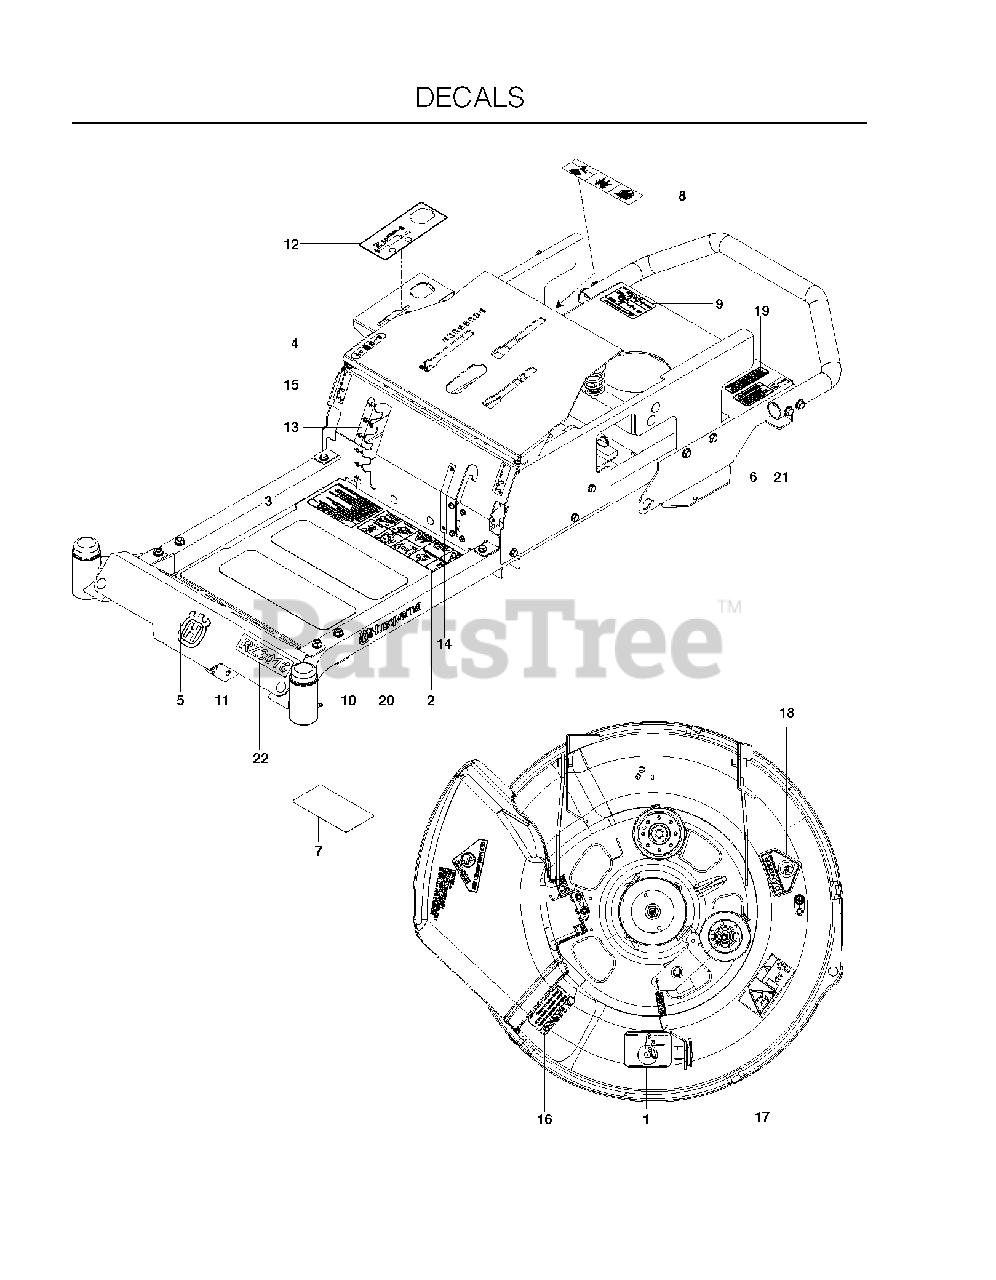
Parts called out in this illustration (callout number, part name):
1	DECAL, BELT ROUTING
2	DECAL, SAFETY WARNING
3	DECAL, WARNING
4	DECAL, PARK BRAKE
5	DECAL.AUGER.HUSQ.CROWN.SNOW
6	DECAL, PROP. 65
7	DECAL, SERVICE
8	EURO DECAL-BATTERY WARNIN6
9	DECAL, DO NOT TOW
10	ANTI-SKID PAD
12	DECAL, CONTROL PANEL HUS
13	DECAL, DECK HEIGHT
14	DECAL, BLADE ENGAGEMENT
15	DECAL, MOTION CONTROL
16	DECAL, CAUTION
17	DECAL, EURO SEVERING
18	DECAL, CPSC
19	DECAL, WARNING SPARK ARRESTOR
20	RP.DECAL.BADGE.170MM.TEXTLOGO
22	DECAL, RZ3016
